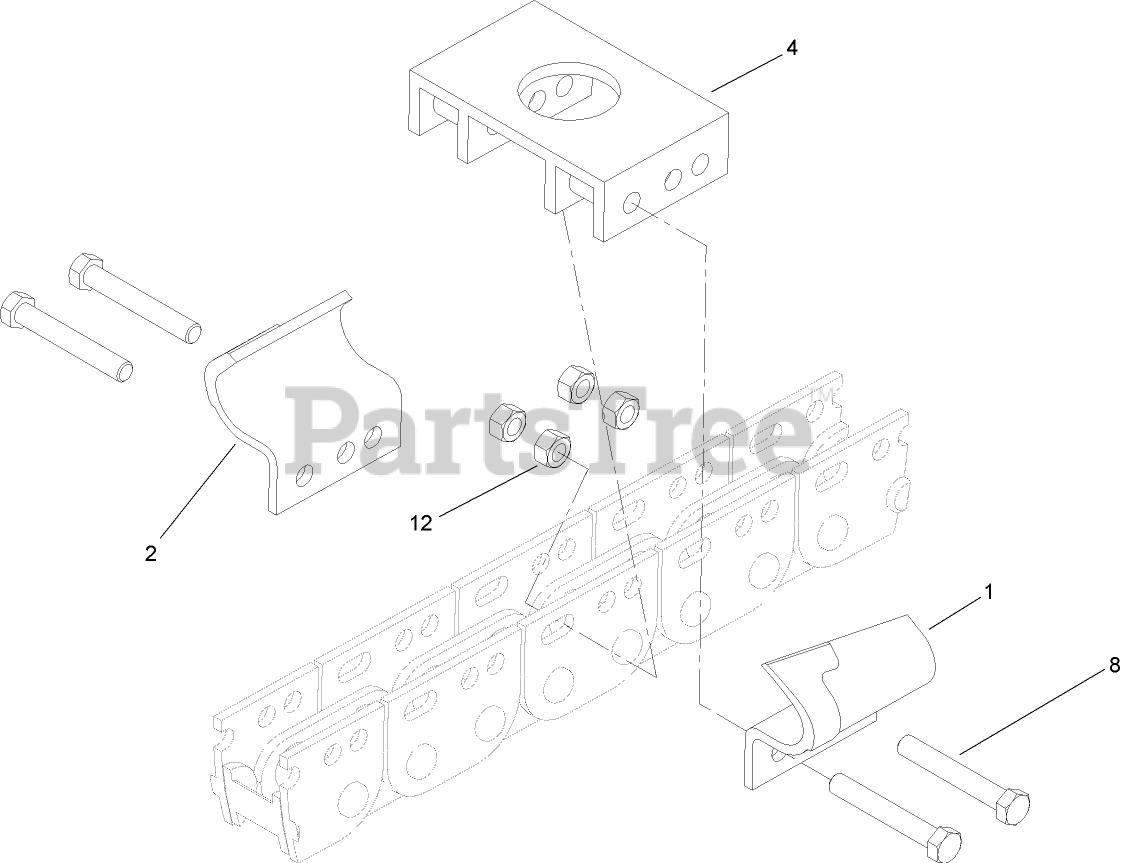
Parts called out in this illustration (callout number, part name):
1	TOOTH-SOIL, LH
2	TOOTH-SOIL, RH
4	ADAPTER-8 Inch
8	SCREW-HH
12	NUT-LOCK
